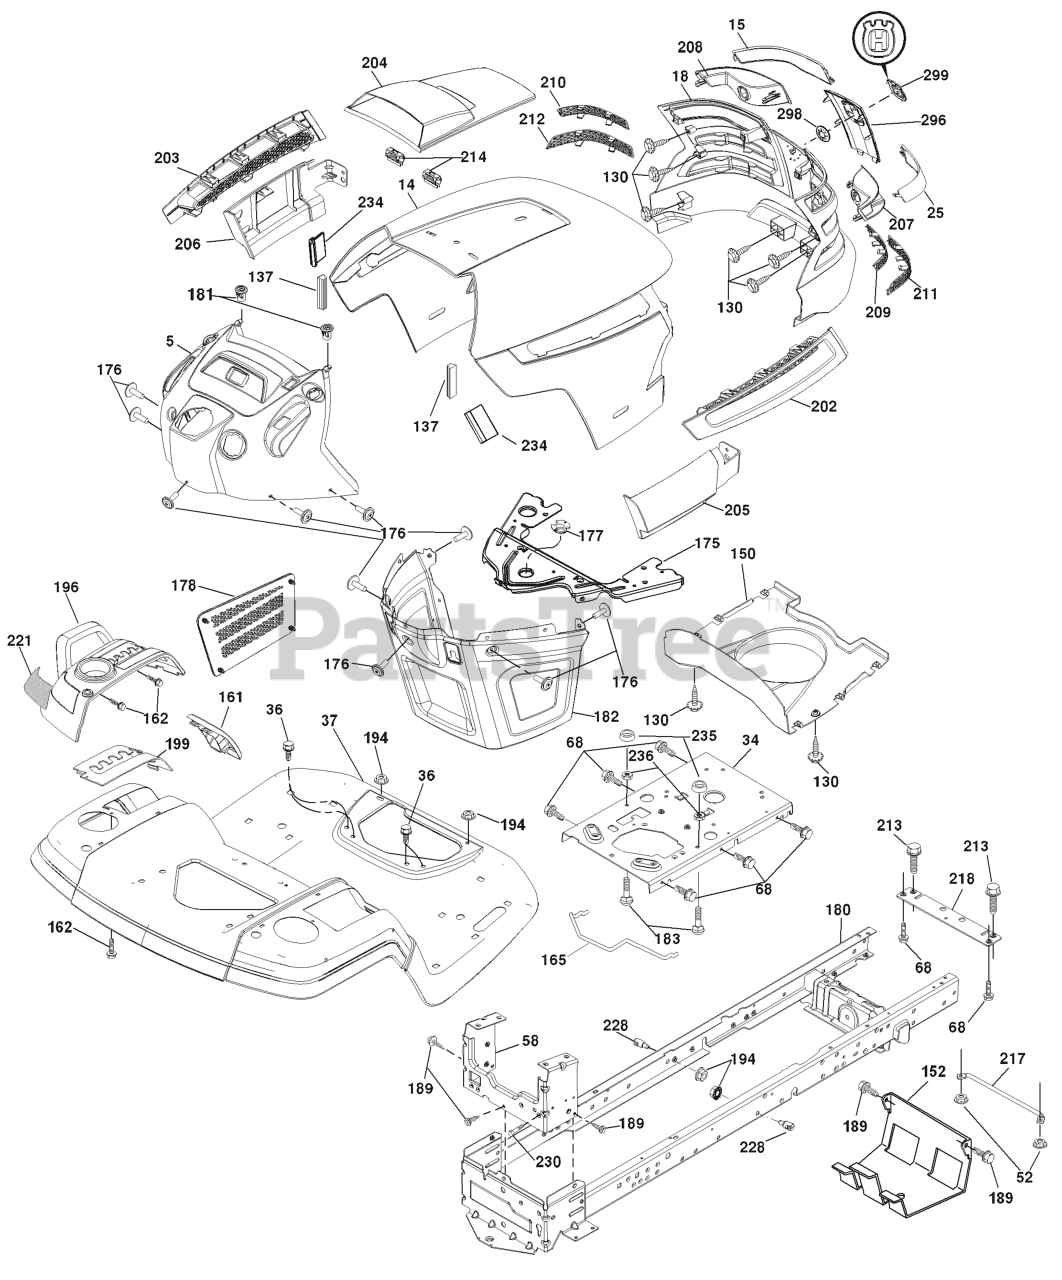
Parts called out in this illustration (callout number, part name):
5	DASH.ASM.HUSQ.GT.E.RECT.W/CK
14	HOOD
15	LENS.LH.TEX.GT.HUSQ.CL
18	GRILL.ASM.HUSQ.TG/CRD.W/TRIM
25	LENS.RH.TEX.GT.HUSQ.CL
34	PLATE.ENGINE.WELDED.CHASSIS
36	SCREW 5/16"
37	FENDER.PNT.TX.GT.CH/FW.ORANGE
52	LOCKNUT
58	DRAWBAR.LOWER.2PC,20"TIRES
68	Screw Thdrol 5/16-18 x 1/2
130	SCREW.#10 X 0.750.BOS
137	BUMPER DASH
150	AIR.DUCT.HOOD.TEX.GT.HUSQ
152	SHIELD.BROWNING.W/TEX
159	SCREW, 3/8-16X3/4
161	CONSOLE.FUEL.WINDOW.HU
162	Screw Hex WSH HI-LO 1/4 x 1/2 unc
165	SUPPORT.TANK.REAR.W/TEX
175	PLATE.CROSSMEMBER.HUSQ
176	SCREW.#10-24X5/8.RN.QU
177	BUSHING, STEERING
178	CARGO.ASM.NET.TXGT.W/C
180	CHASS.WLDMNT.TLT.12GA/2PC.20"
181	BUSHING.MNT.FEND.CRGO.
182	DASH.LOWER.COMMON.12V.ADAPTOR
183	BOLT.5/16-18X1-1/4 FULL.THREAD
189	SCREW
194	NUT LOCK HEX FLANGE 5/16-18
196	Console Asm. Deck Lift
199	PLATE.DECK.LIFT.HUSQVARNA.GT
202	VENT.SIDE.HOOD.HUSQ.RH.GREY
203	VENT.SIDE.HOOD.HUSQ.LH.GRAY
204	HOOD VENT
205	SKIRT.HOOD.SIDE.HUSQ.RH.GREY
206	SKIRT.HOOD.SIDE.HUSQ.LH.GREY
207	BEZEL.RH.TEX.GT.HUSQ
208	BEZEL.LH.TEX.GT.HUSQ
209	INSERT.HEX.GRILL.HUSQ.GREY
210	INSERT.HEX.GRILL.HUSQ.
211	INSERT.HEX.GRILL.HUSQ.
212	INSERT.HEX.GRILL.HUSQ.
213	BOLT
214	CLIP.RETAINER.TINNER.
217	ROD.PIVOT.HOOD
218	X-PIECE.HOOD.STOP.NON/
221	REFLECTOR.LH.TEX GT HU
228	STUD.FASTNER.W/ANTI-ROTATE
230	SHOULDER BOLT 5/16-18TT
234	BUMPER.HOOD.TEX.HUSQVARNA
235	SPACER FENDER
236	NUT.CENTERLOCK.5/16-
296	TRIM.HUSQ.TG/CRD.SERVICE
298	NUT PUSH M
299	RP LOGO
